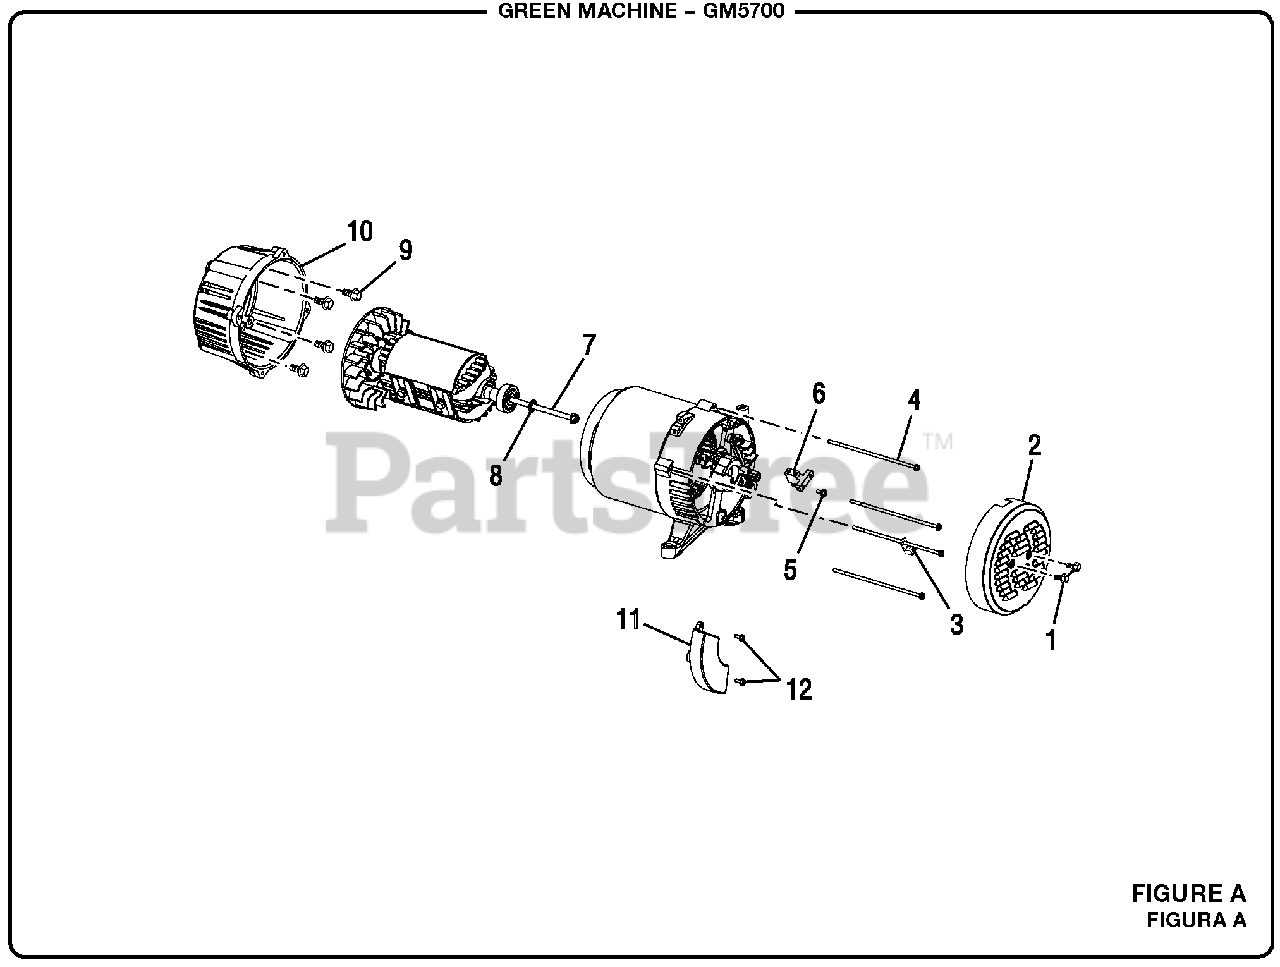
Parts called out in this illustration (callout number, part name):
1	Bolt (M5 x 10, Flange Hd.)
2	Brush Cover
3	Ground Lug
4	Bolt, Stator 5.7kW
5	Bolt, Mounting Brush Assembly
6	Brush Assembly
7	Bolt (5/16-24 x 6-5/8 in., Hex Hd.)
8	Lock Washer (5/16 in.)
9	Bolt, Wiz (3/8-18 x 1-1/4 in.)
10	Adapter Housing
11	Bolt, Mounting AVR
12	Automatic Voltage Regulator
